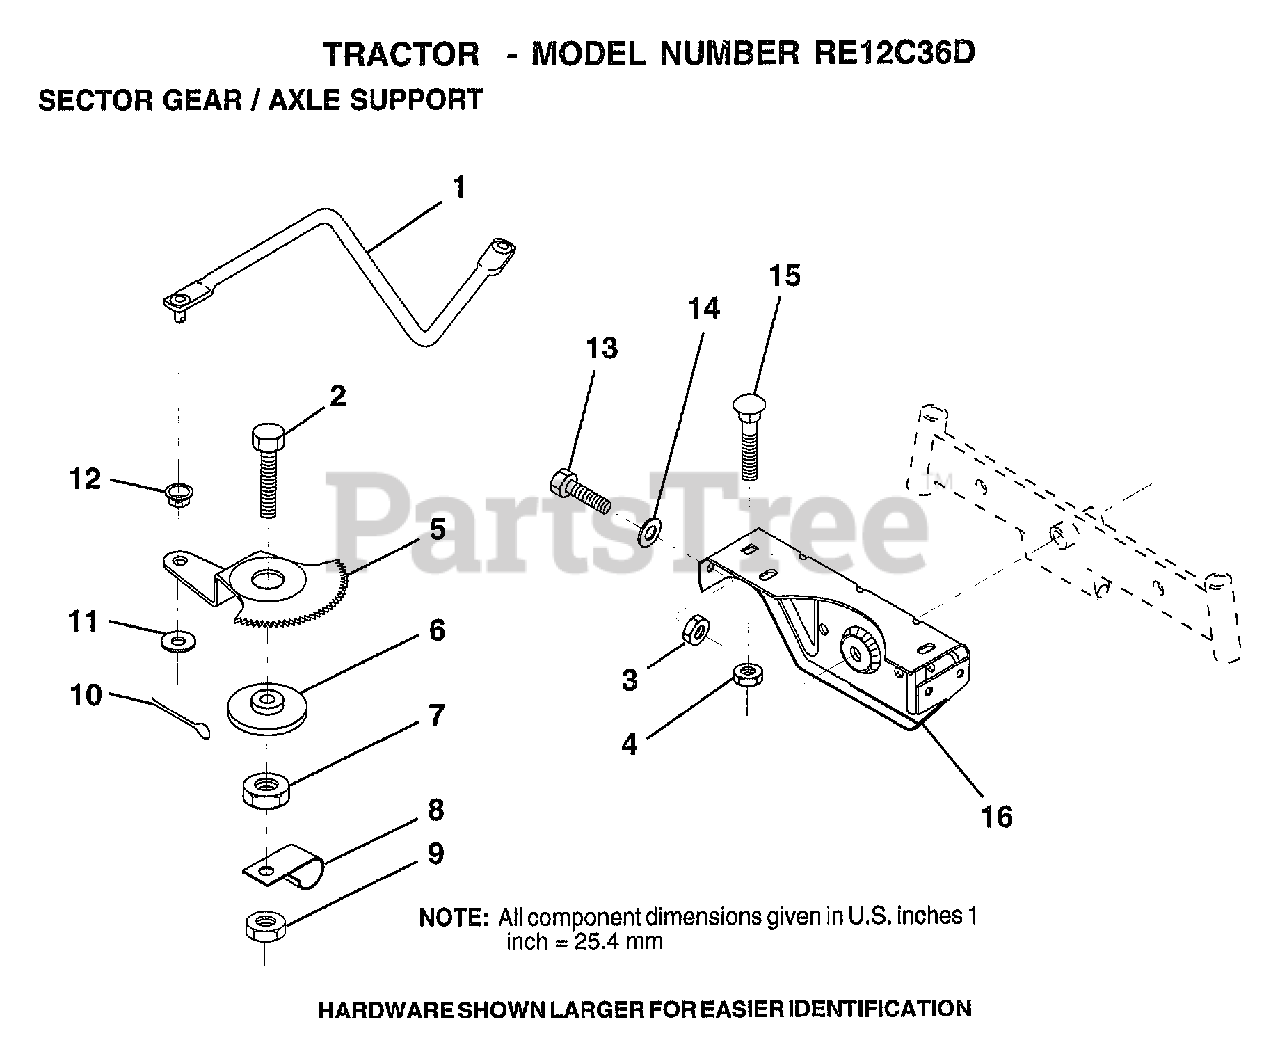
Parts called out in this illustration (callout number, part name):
1	DRAG LINK
2	"BOLT,HEX"
5	GEAR SECTOR
6	BUSHING
7	NUT
8	CLIP INSULATOR
9	NUT LTV
10	COTTER PIN
11	WASHER
12	BUSHING.DRAGLINK
13	BOLT
14	WASHER
15	BOLT
16	SUPT AXLE FRONT
